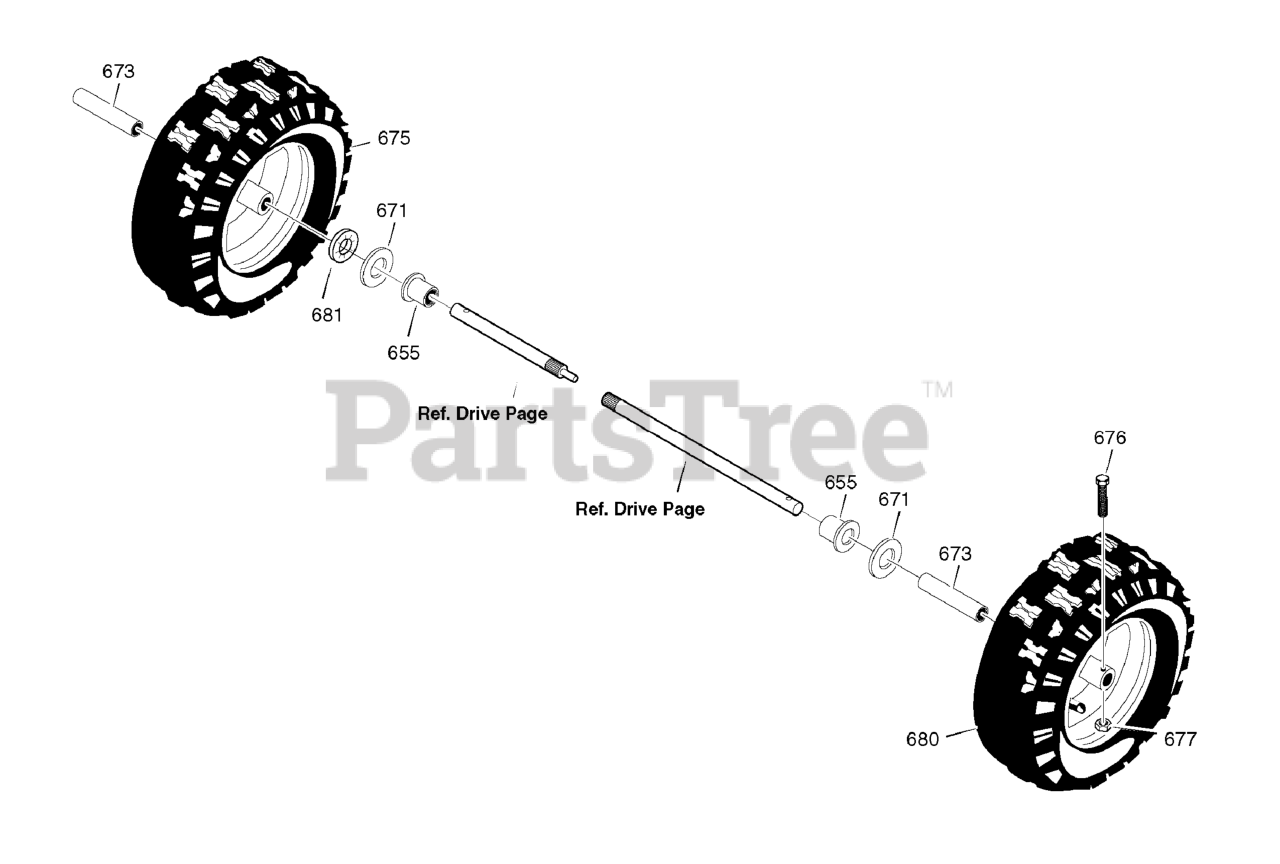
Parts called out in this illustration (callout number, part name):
655	BEARING, AXLE
671	FLATWASHER
673	BUSHING, WHEEL
675	TIRE & RIM, LEFT
676	SCREW, 1/4-20 X 1.75 HH
677	NUT, 1/4-20 HEX NYLOCK
680	TIRE & RIM, RIGHT
681	RETAINER
